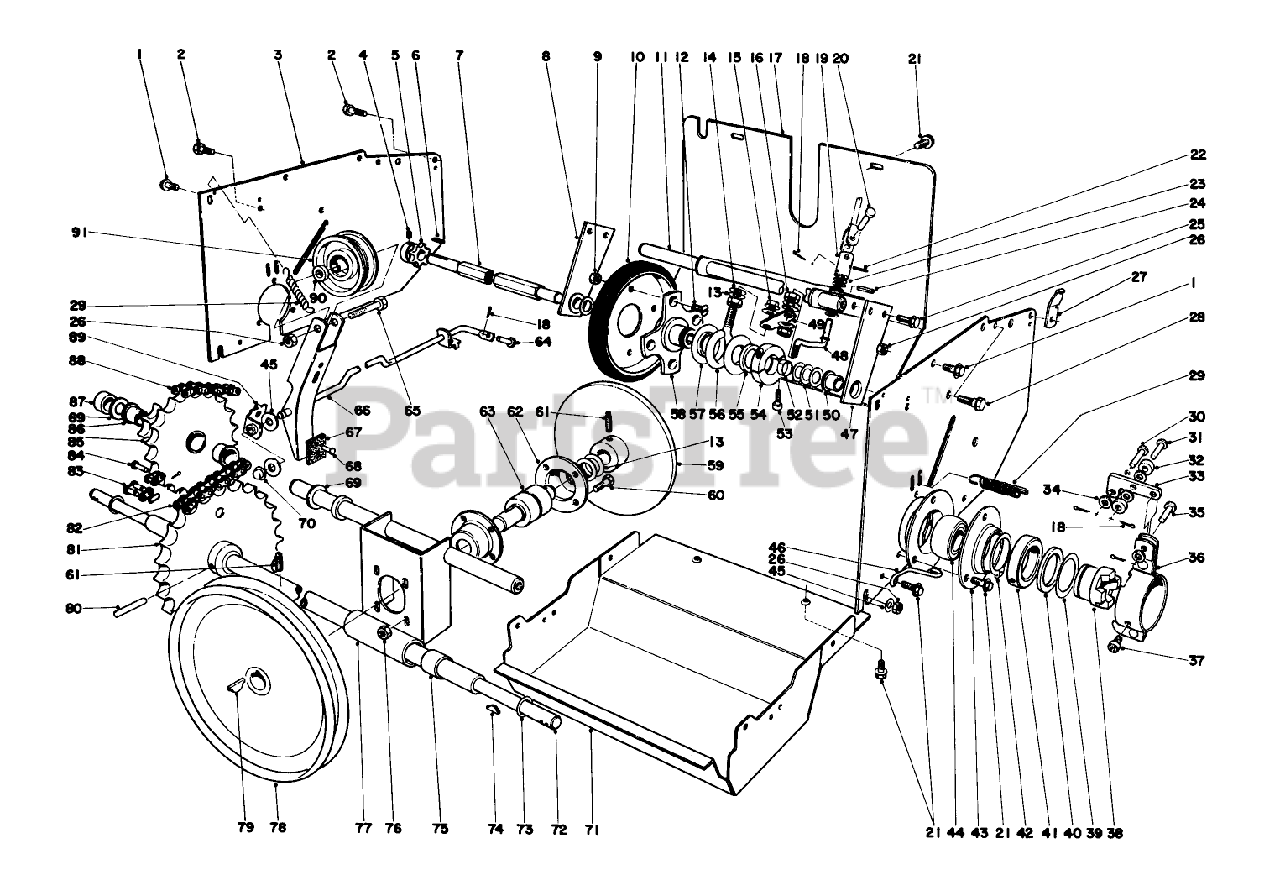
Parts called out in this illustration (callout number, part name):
1	SCREW-HHF
2	SCREW-HHFTF
4	SCREW-HSH
5	SPROCKET
8	RH SHAFT MT & BSHG
12	SCREW-FH, S
13	Washer
15	NUT-LOCK, FLANGE
17	REAR COVER *R
18	PIN-COTTER
21	SCREW-HWH
22	PIN-SPRING
24	PIN-ROLL
25	SCREW-THD ROLL, HWH
29	EXTENSION SPRING
30	PIN-CLEVIS
31	PIN-CLEVIS
33	CLUTCH CAM ARM
34	WASHER-FLAT
35	PIN-CLEVIS
36	CLUTCH MT BRKT ASM
37	Hex Socket Capscrew
39	THRUST WASHER
40	THRUST BEARING
42	RING-RETAINING, EXTERNAL
44	BEARING
45	WASHER-FLAT
48	CONNECTION ROD
49	SHIFT ROD PIVOT
50	BUSHING
51	WASHER-FLAT
53	SCREW-HSH
54	Collar
55	WASHER-THRUST
56	SLIDER RING COLLAR
59	Friction Plate
60	SCREW-HH
61	Set Screw
62	HOUSING BEARING
63	Friction Plate Shaft
64	PIN-CLEVIS
65	SCREW-HH
68	.185 DIA X .375 RT +
69	WASHER-THRUST
71	LOWER SHIELD *R
73	WASHER
75	BUSHING
76	NUT-KEPS
79	KEY-WOODRUFF
80	PIN-GROOVE
83	Connecting Link
84	1/4 OFFSET LINK
87	SPACER-IDLER
88	1/4 X 42 CHAIN W/LINK
91	Idler Pulley
